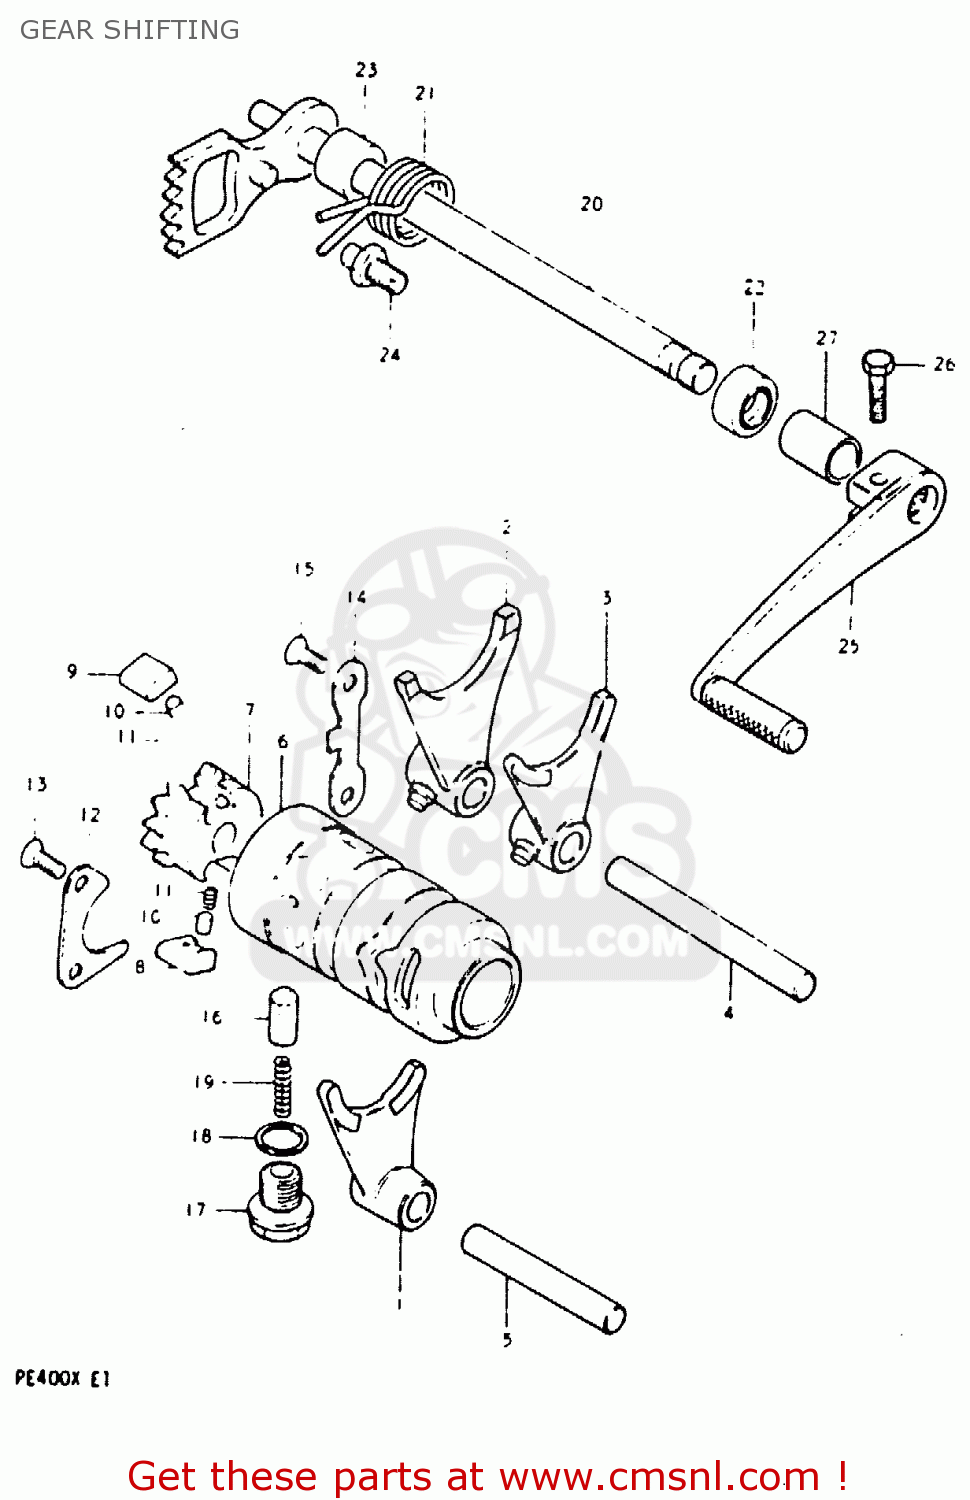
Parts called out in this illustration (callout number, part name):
1	FORK,GEAR SHIFT NO.1
2	FORK,GEAR SHIFT NO.2
3	FORK,GEAR SHIFT NO.3
4	SHAFT,GEAR SHIFT FORK
5	SHAFT,GEAR SHIFT FORK
6	CAM,GEAR SHIFT
7	RETAINER,GEAR SHIFT CAM
8	PAWL,GEAR SHIFT NO.1
9	PAWL,GEAR SHIFT NO.2
10	PIN(5X8)
11	SPRING
12	LIFTER,GEAR SHIFT PAWL
13	SCREW
14	GUIDE,GEAR SHIFT CAM
15	SCREW
16	STOPPER,GEAR SHIFTING
17	BOLT,GEAR SHAFT CAM STOPPER
18	GASKET(14X19.2X2) (NAS)
19	SPRING
20	SHAFT,GEAR SHIFT
21	SPRING
22	OIL SEAL
23	SPACER(12X20X15.3)
24	STOPPER,GEAR SHIFT CAM
25	LEVER ASSEMBLY,GEAR SHIFTING
26	BOLT
27	CUSHION
